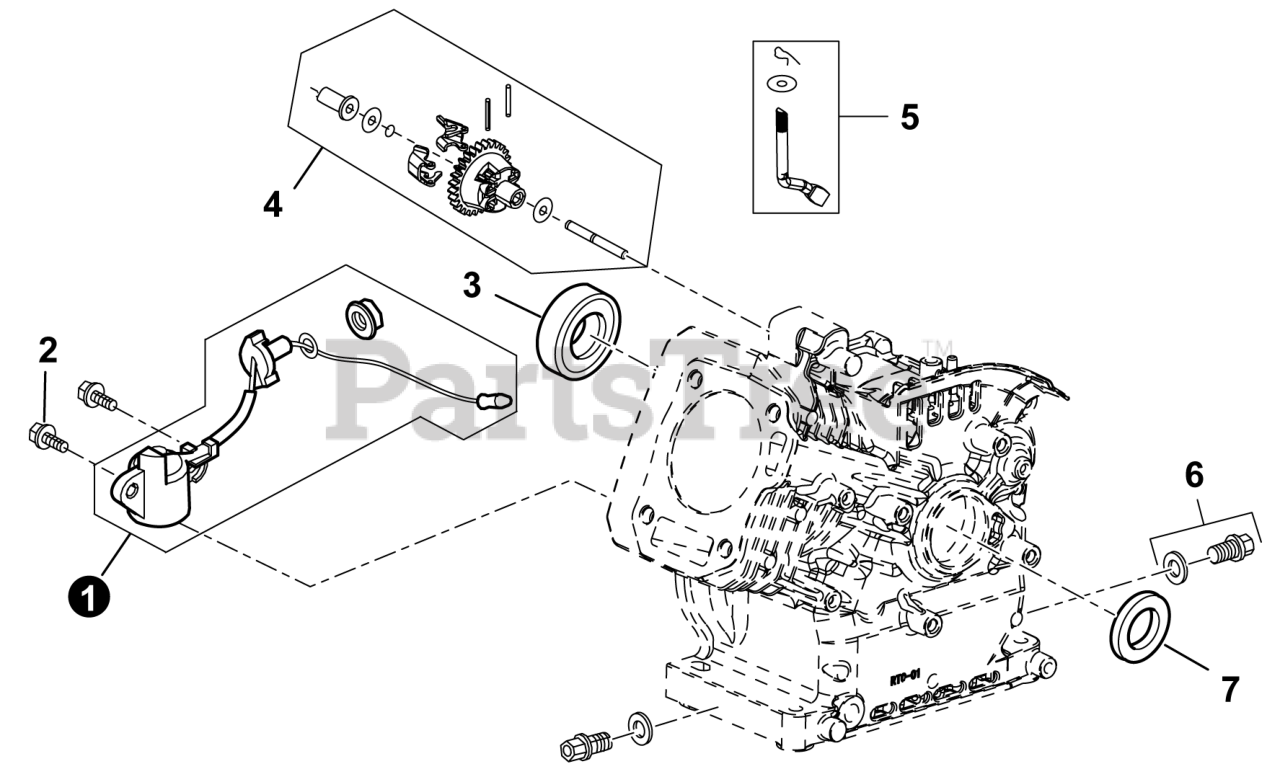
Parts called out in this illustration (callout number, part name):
1	SENSOR, ENGINE OIL
3	BEARING, CRANKSHAFT
4	GEAR ASSY., GOVERNOR
5	ARM, GOVERNOR
6	PLUG, OIL DRAIN
7	SEAL, OIL
